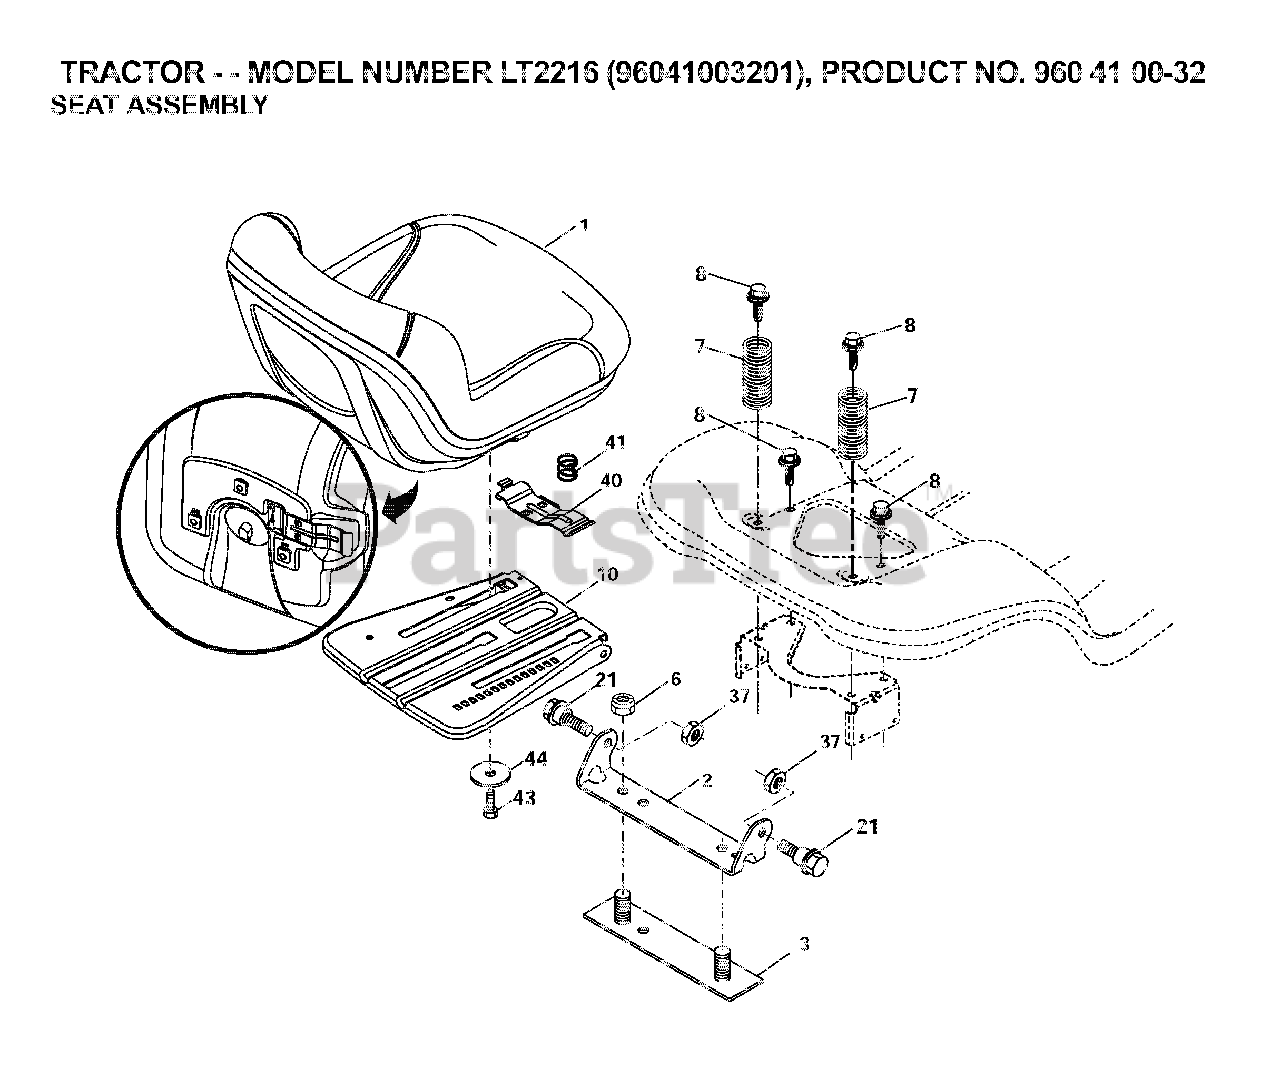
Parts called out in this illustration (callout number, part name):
1	SEAT.TG130.BLACK.NO/LOGO.
2	BRKT.PIVOT.FENDER
6	NUT
7	SPRING COMPRESSION
8	BOLT, 5/16-18 X 1 3/4
10	PAN.ASM.SEAT.3PT
21	BOLT.SHOULDER.5/16-18
37	NUT.71038.31-18.HEX.NYLOCK
40	HANDLE.SLIDE.SEAT.TEX.BLACK
41	SPRING.LATCH.SEAT.TEX
44	WASHER 13/32 X 2-3/8 X 12GA
